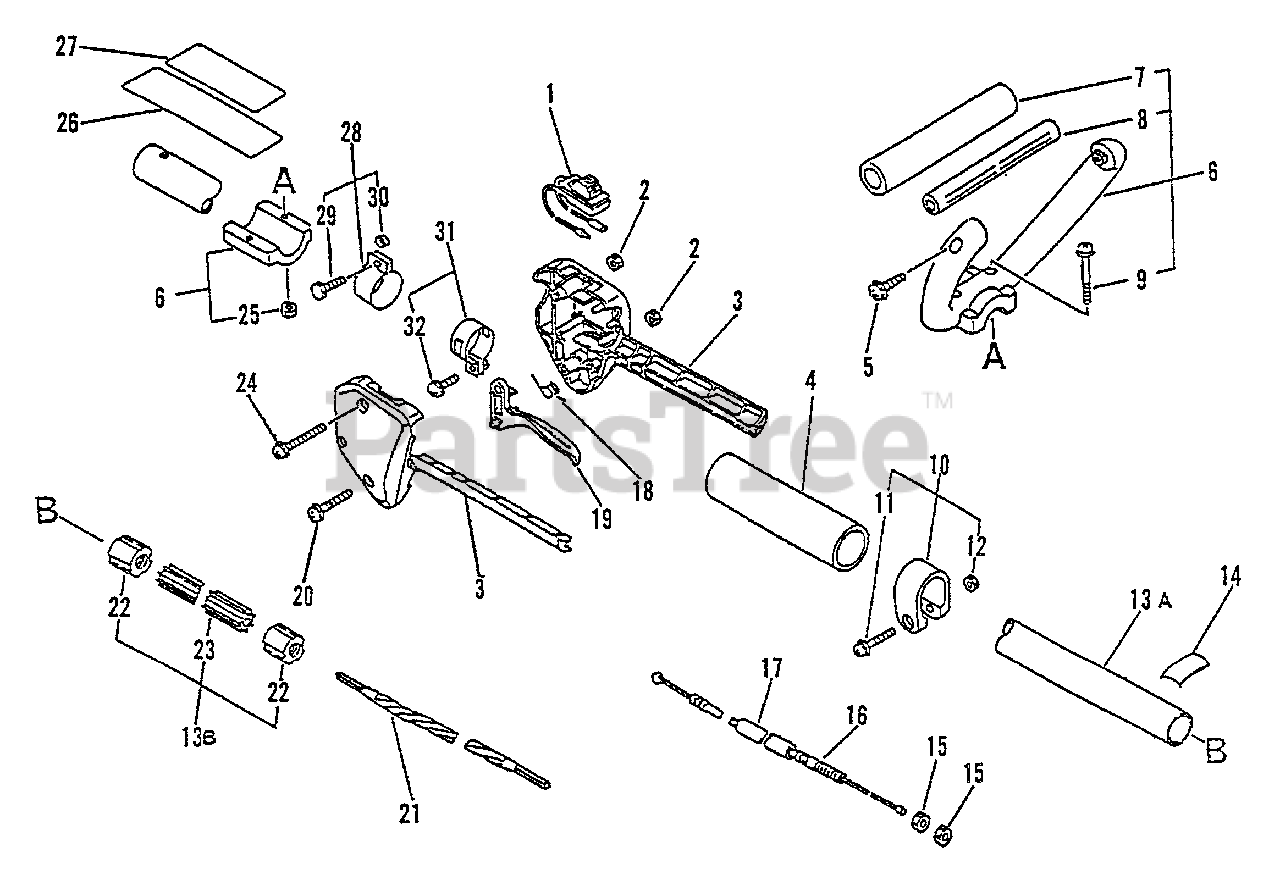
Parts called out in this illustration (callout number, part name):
1	IGNITION SWITCH ASSY
3	CONTROL HANDLE KIT
4	GRIP, HANDLE
5	SCREW - 5X30
6	LOOP HANDLE ASSY
7	GRIP, HANDLE
9	SCREW - 6X35
10	CLAMP KIT
11	SCREW - 5X28
13	MAIN PIPE ASSY
13A	MAIN PIPE ASSY
13B	MAIN PIPE ASSY
14	LABEL - ALIGNMENT
16	CABLE, THROTTLE
17	TUBE - VINYL
18	SPRING, TRIGGER
19	TRIGGER, THROTTLE
20	SCREW - 5X25
21	DRIVESHAFT - FLEXIBLE
23	LINER - FLEXIBLE
24	SCREW - 5X35
25	LOCKNUT - 6
26	LABEL - CAUTION
27	LABEL - CAUTION
28	CLAMP
29	BOLT - 5X18
31	CLAMP KIT
32	SCREW - 5X14
